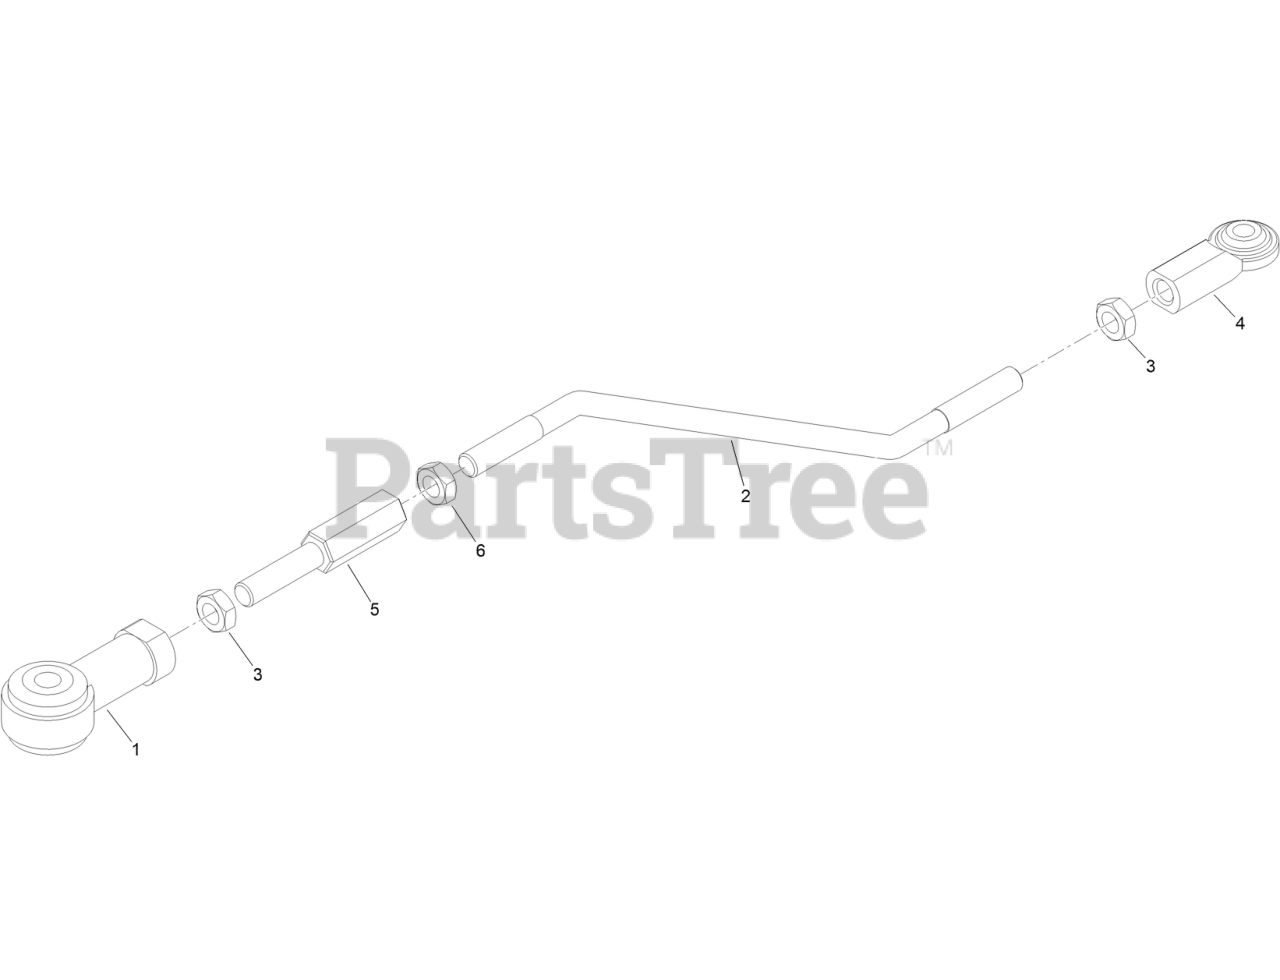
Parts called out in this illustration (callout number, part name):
1	END-ROD, ISOLATED
2	ROD-LINKAGE, REAR
3	NUT-HJ
4	JOINT-BALL, END
5	ROD-ADJUSTMENT
6	NUT-HEX JAM, LH
